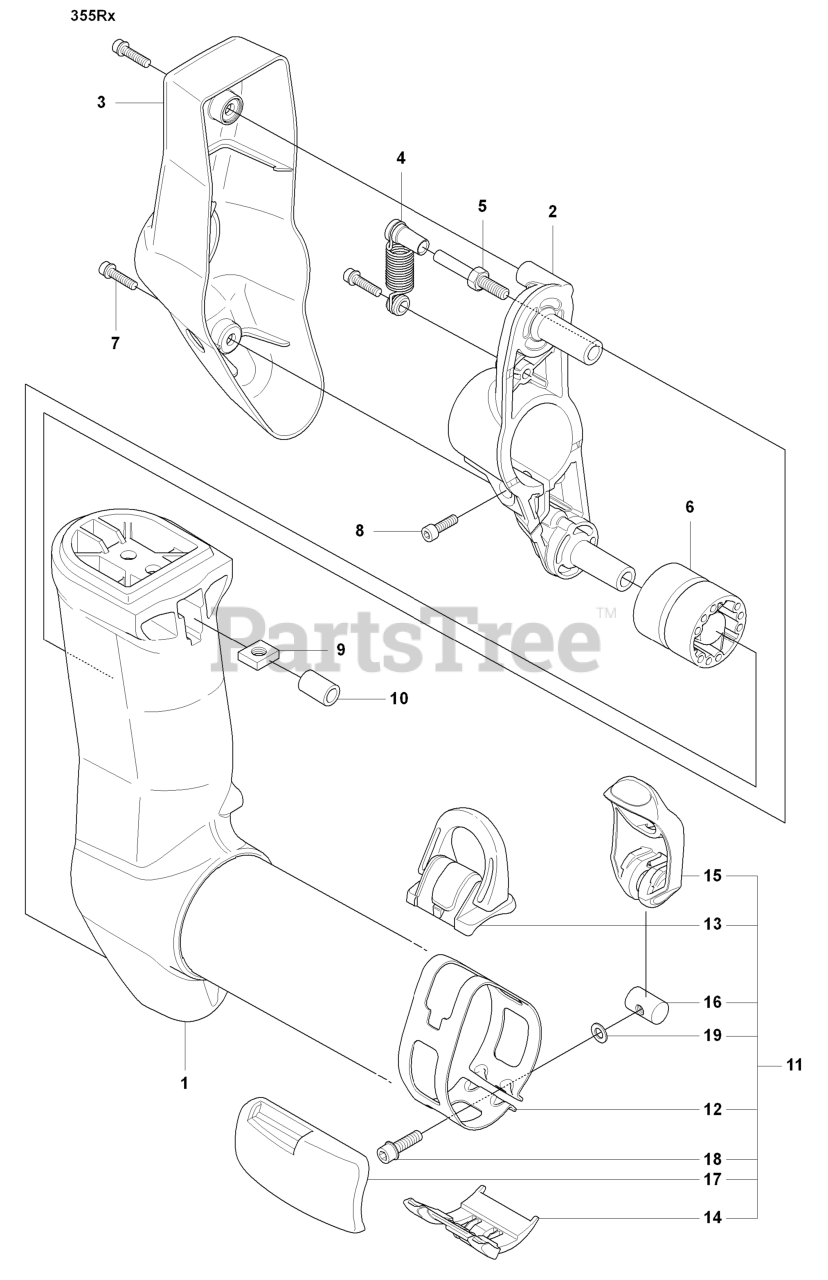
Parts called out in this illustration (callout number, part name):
1	SUSPENSION
4	SPRING
5	PARALLEL PIN
6	ANTIVIBE ELEMENT
7	SCREW IHSCFM
11	LOOP
14	GUIDE RAIL
17	WEAR PROTECTION
19	WASHER 5.3X12
